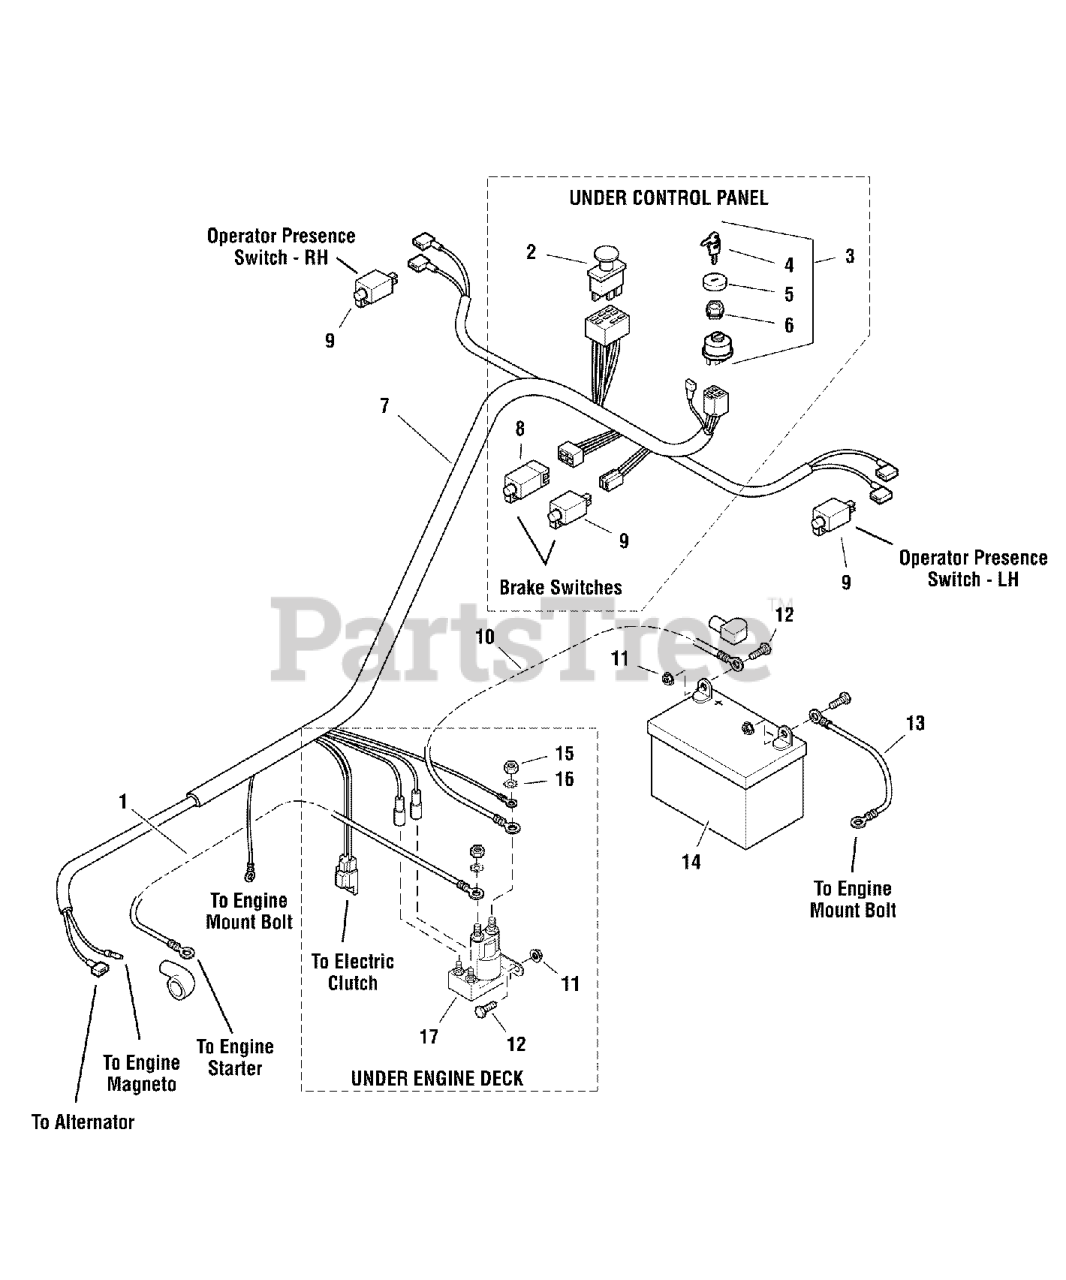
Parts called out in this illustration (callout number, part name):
1	POSITIVE (+) BATTERY CABLE, 30"
2	SWITCH, BLADE ENGAGEMENT
3	SWITCH, IGNITION, 6 POST
4	KEY, IGNITION MOLDED SET
5	COVER, PLASTIC, SNAP ON
6	PLASTIC NUT
7	WIRE HARNESS, MAIN, HYDROCUT
8	SWITCH, Plunger, NO/NO
9	SWITCH, PLUNGER, N.C.
10	POSITIVE (+) BATTERY CABLE, 22"
11	NUT, 1/4-20 HEX SERR. FLANGE
12	BOLT, 1/4-20 x 3/4
13	BATTERY CABLE, NEG, 22, 1/4-5/16
14	BATTERY, Lawn & Garden, 12V (BCIU1, 340 CCA)
15	NUT, Hex Jam, 5/16-24
16	WASHER, Light Lock, 5/16
17	SOLENOID
